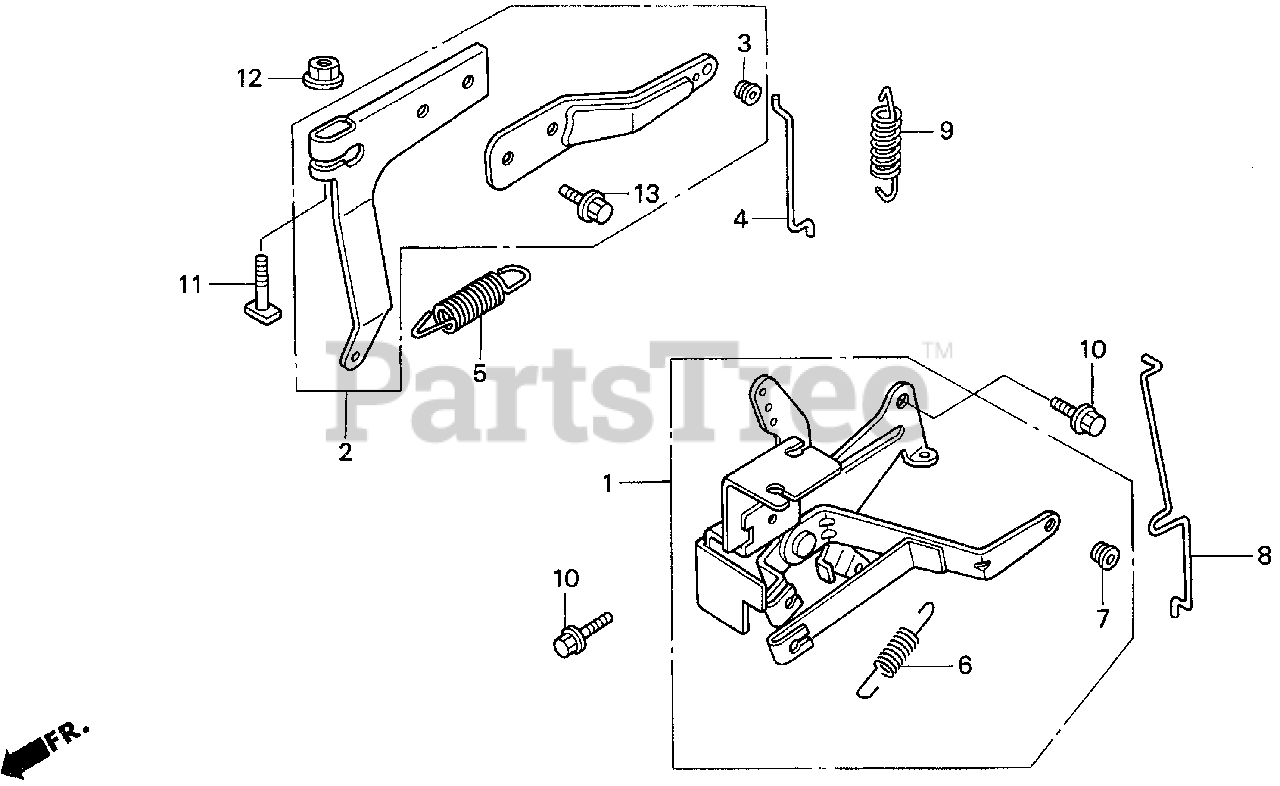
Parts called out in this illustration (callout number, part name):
2	ARM, GOVERNOR
3	COLLAR, LEVER
4	ROD, GOVERNOR
5	SPRING, GOVERNOR
6	SPRING, CONTROL LEVER RETURN
7	COLLAR, LEVER
8	ROD, CHOKE
9	SPRING, THROTTLE RETURN
10	BOLT, FLANGE (6X14)
11	BOLT, GOVERNOR ARM
12	NUT, FLANGE (6MM)
13	BOLT, FLANGE (6X8)
